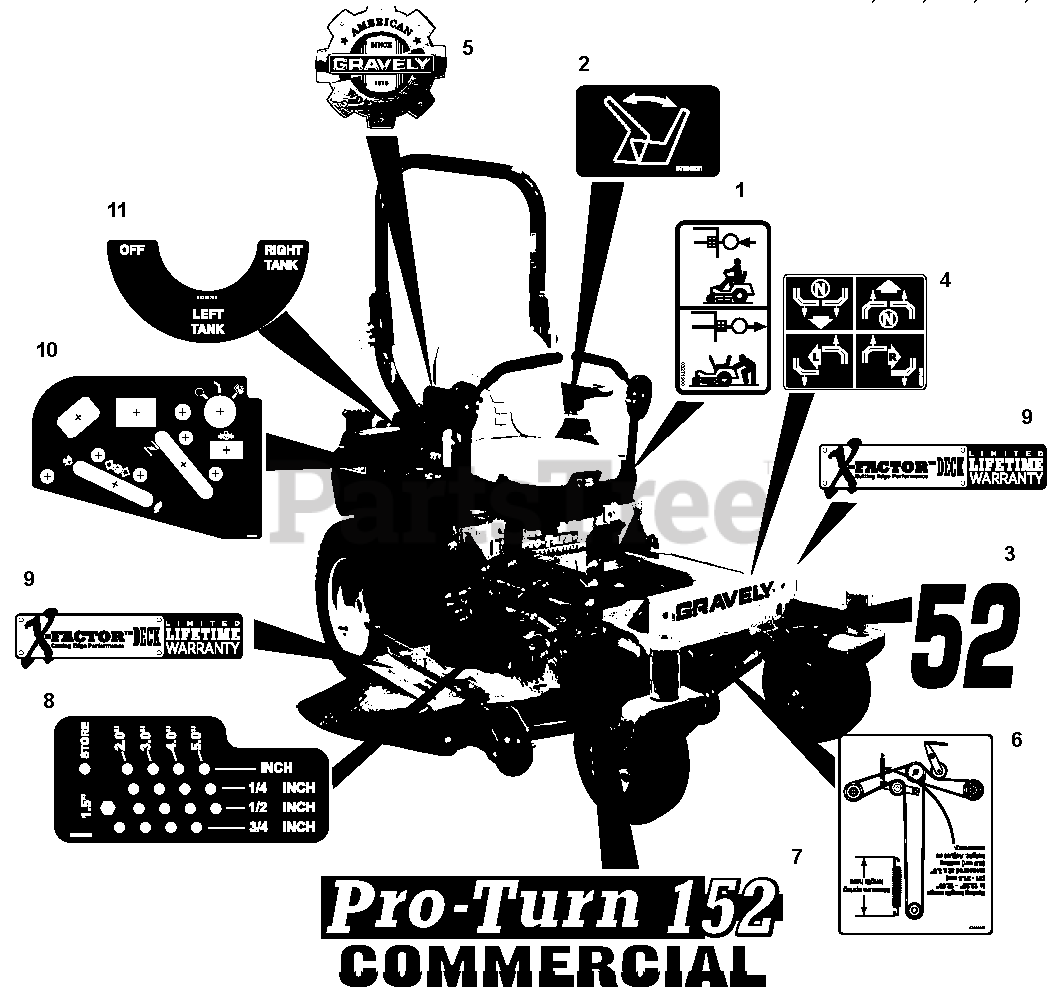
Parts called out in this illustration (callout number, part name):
1	Decal, Transmission Disconnect
2	Decal, Seat Release
3	Decal, 48 (991079), 095
4	Decal, Instructional-Steering
5	Decal, Gravely Heritage, Large
6	Decal, Belt Routing (991079, 080, 095, 096)
7	Decal, Pro-Turn 148 (991079, 095)
8	Decal, Height of Cut
9	Decal, X-Factor Deck
10	Decal, Control Panel (991079, 080, 081)
11	Decal, Fuel Valve
